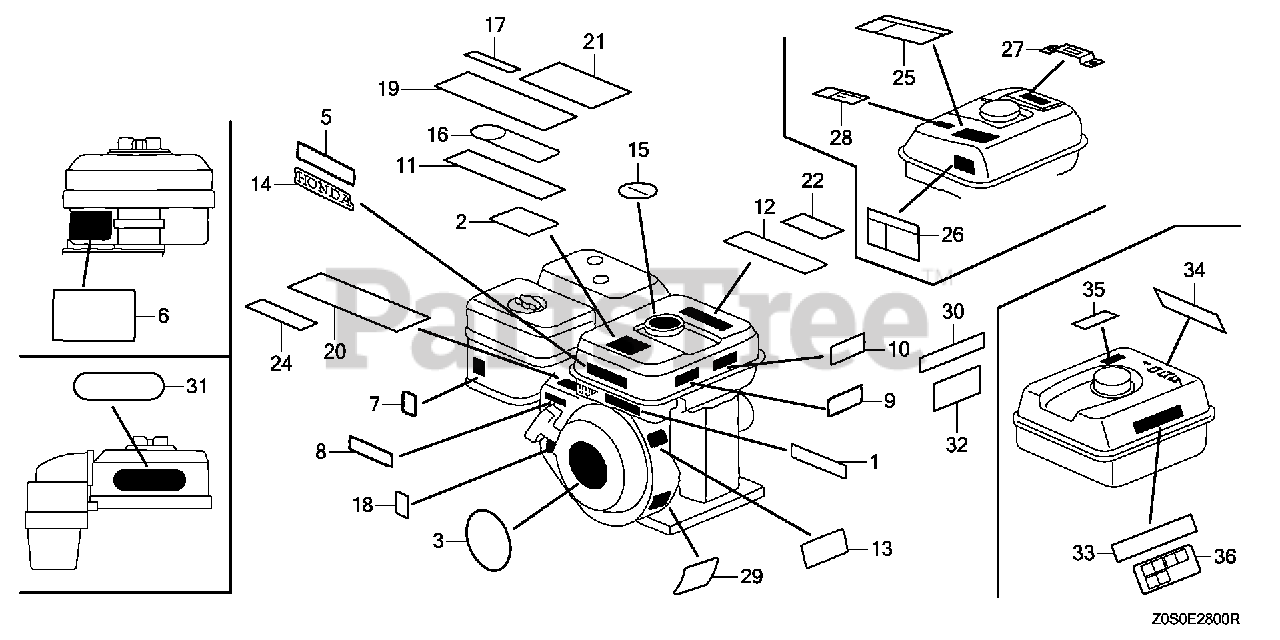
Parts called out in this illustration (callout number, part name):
3	EMBLEM (GX120)
7	MARK, CHOKE
18	LABEL, WARNING (NOT CERTIFIED FOR SALE)
32	MARK, OPERATOR CAUTION
